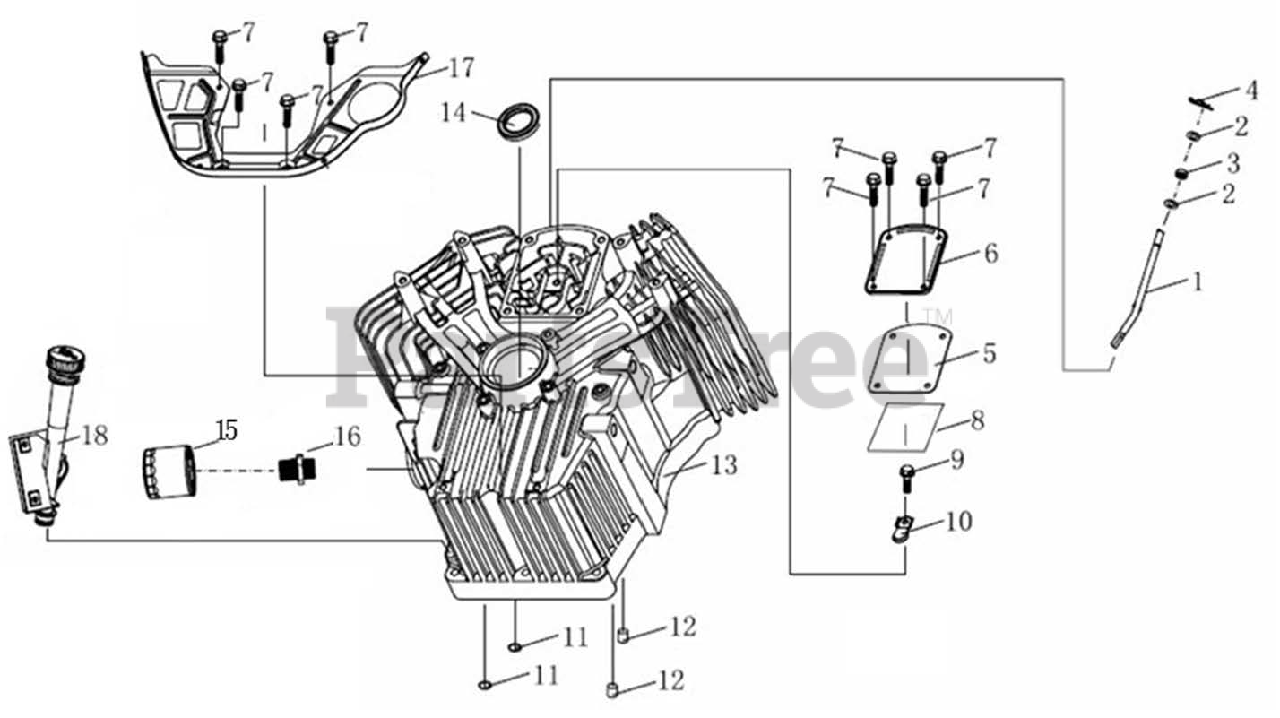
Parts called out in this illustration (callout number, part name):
1	SPEED REGULATING ARM
2	FLAT WASHER
3	OIL SEAL
4	PIN, LOCK
5	PACKING, BREATHER CHAMBER
6	CAP,BREATHER CHAMBER
7	BOLT, FLANGE
8	FILTER BLOCK
9	BOLT, FLANGE
10	LEAF VALVE
11	SEAL RING
12	LOCATION PIN
13	CRANKCASE BODY
14	OIL SEAL
15	FILTER, OIL LONCIN
16	OIL FILTER MOUNTING BOLTS
17	SIDE PLATE
18	OIL RULE COMBINATION
